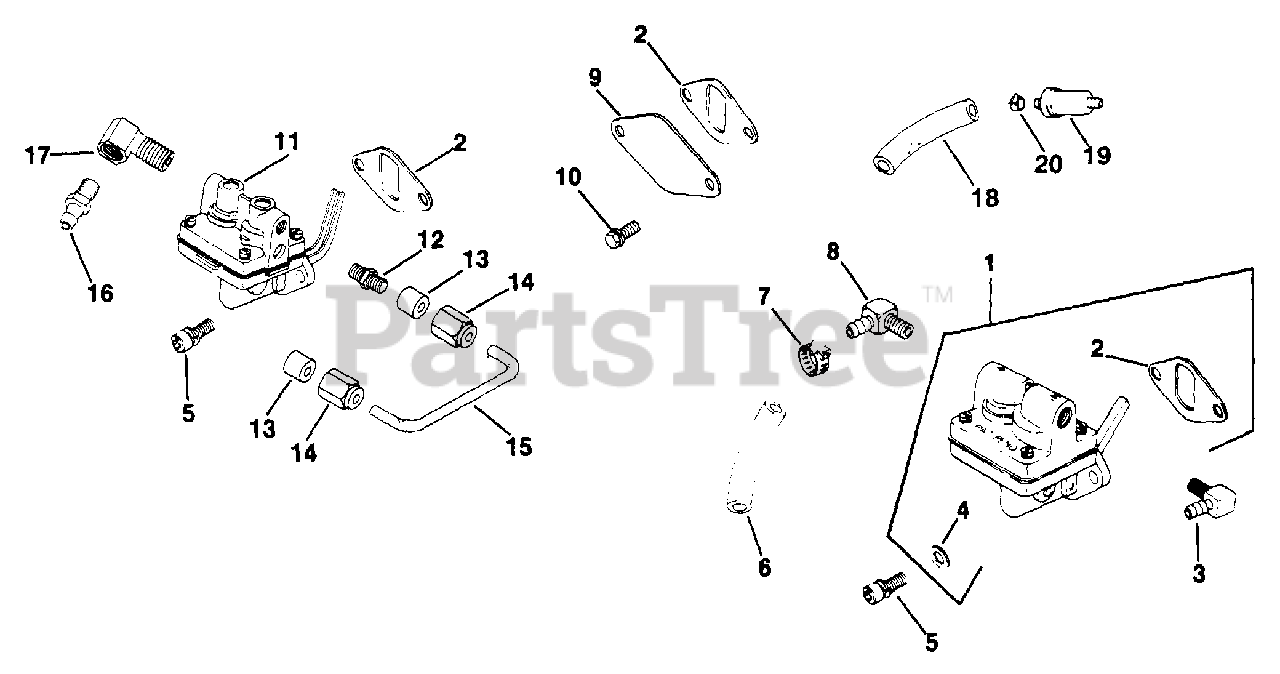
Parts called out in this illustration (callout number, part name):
1	KIT, FUEL PUMP
3	CONNECTOR, 90 DEG. - DISCONTINUED
4	WASHER, FLAT 1/4" (O.D. 1/2")
5	SCREW, SEMS 1/4-20X3/4"
6	LINE - DISCONTINUED
7	CLAMP, HOSE 1/2" USE 25 237 14-S
8	CONNECTOR, 90 DEG. HOSE
16	CONNECTOR USE 25 326 03-S
